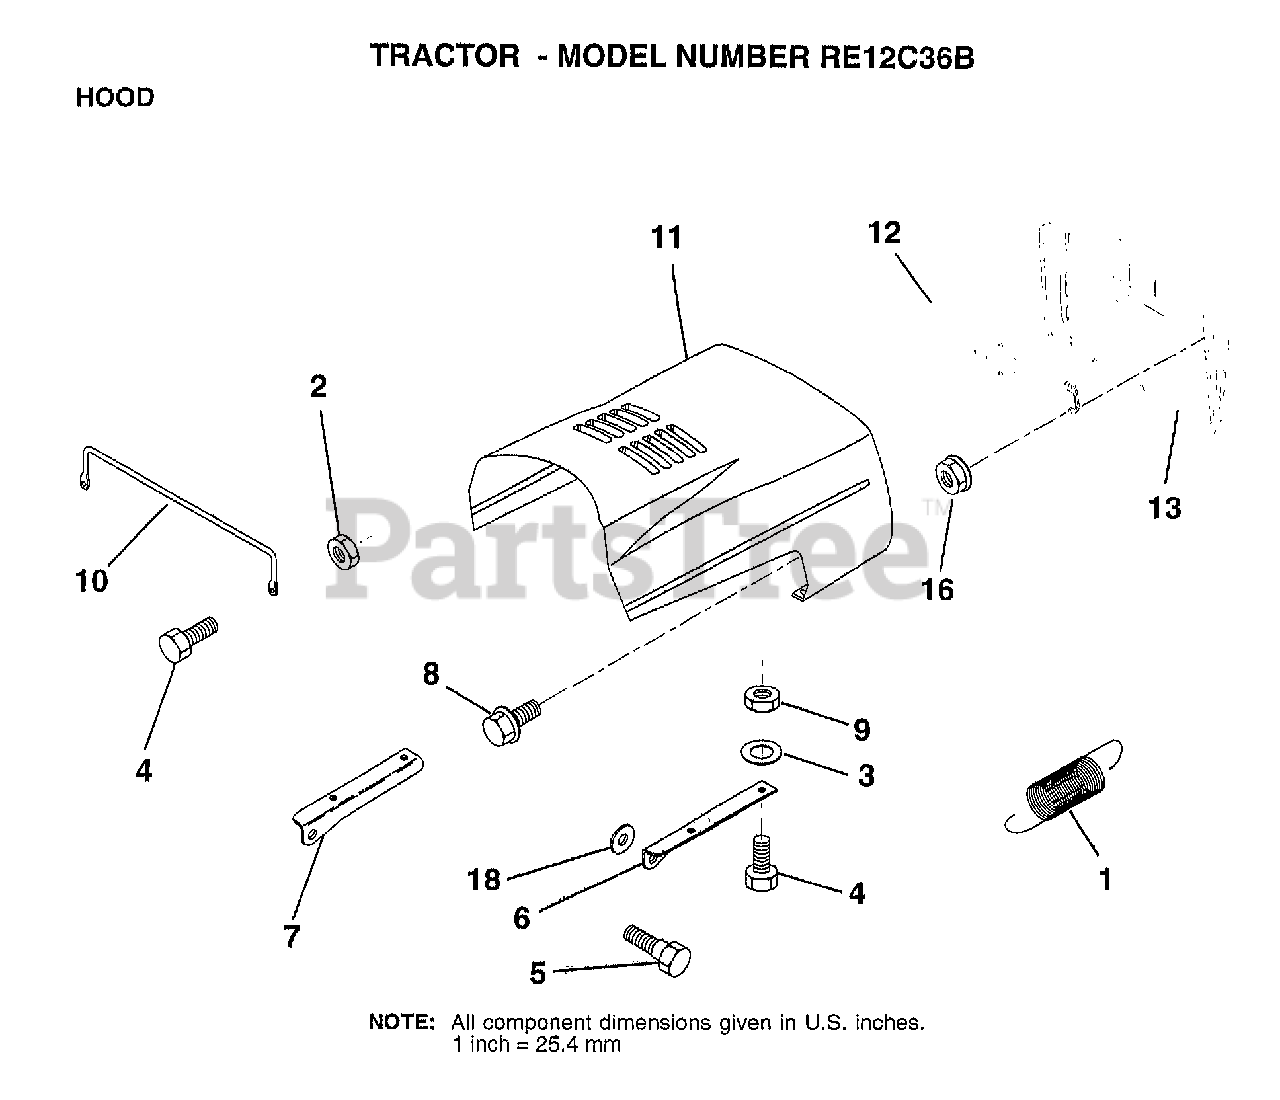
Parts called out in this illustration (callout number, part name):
1	EXT SPRING
2	NUT
3	WASHER
5	BOLT.SHLD.5/16-18
6	BRKT HOOD RH
7	BRKT HOOD LH
8	"SCREW,HWHD.HI-LO#13-16X3/4"
9	NUT
10	"BRACE,HOOD"
11	HOOD
13	GRILL (BLACK)
16	NUT
18	WASHER
